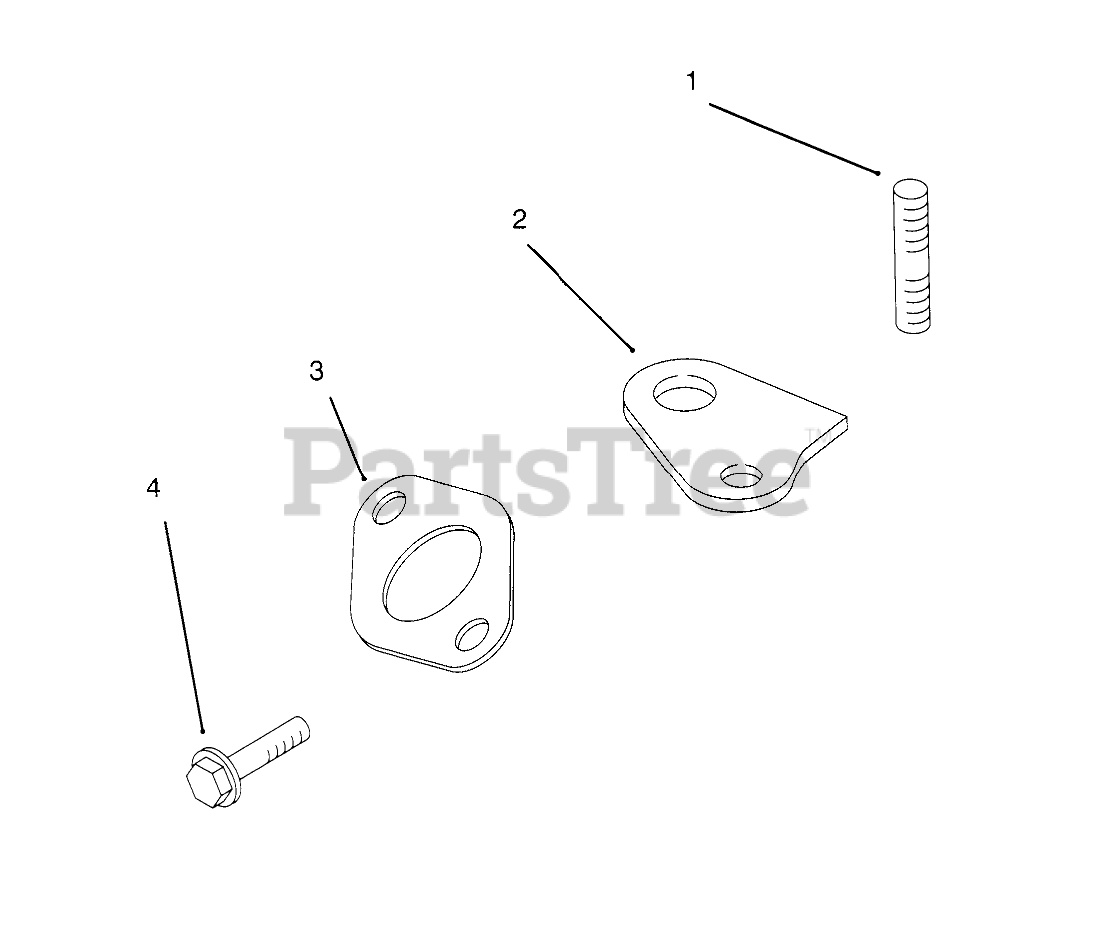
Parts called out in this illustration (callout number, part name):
1	Stud M8x1.25x20 (Only On: 72042,72043,72062,72063)
2	Strap-Lifting (Only On: 72042,72043,72062,72063)
3	Gasket-Exhaust Manifold (Only On: 72042,72043,72062,72063)
4	Screw-Valve Cover (Only On: 72042,72043,72062,72063)
